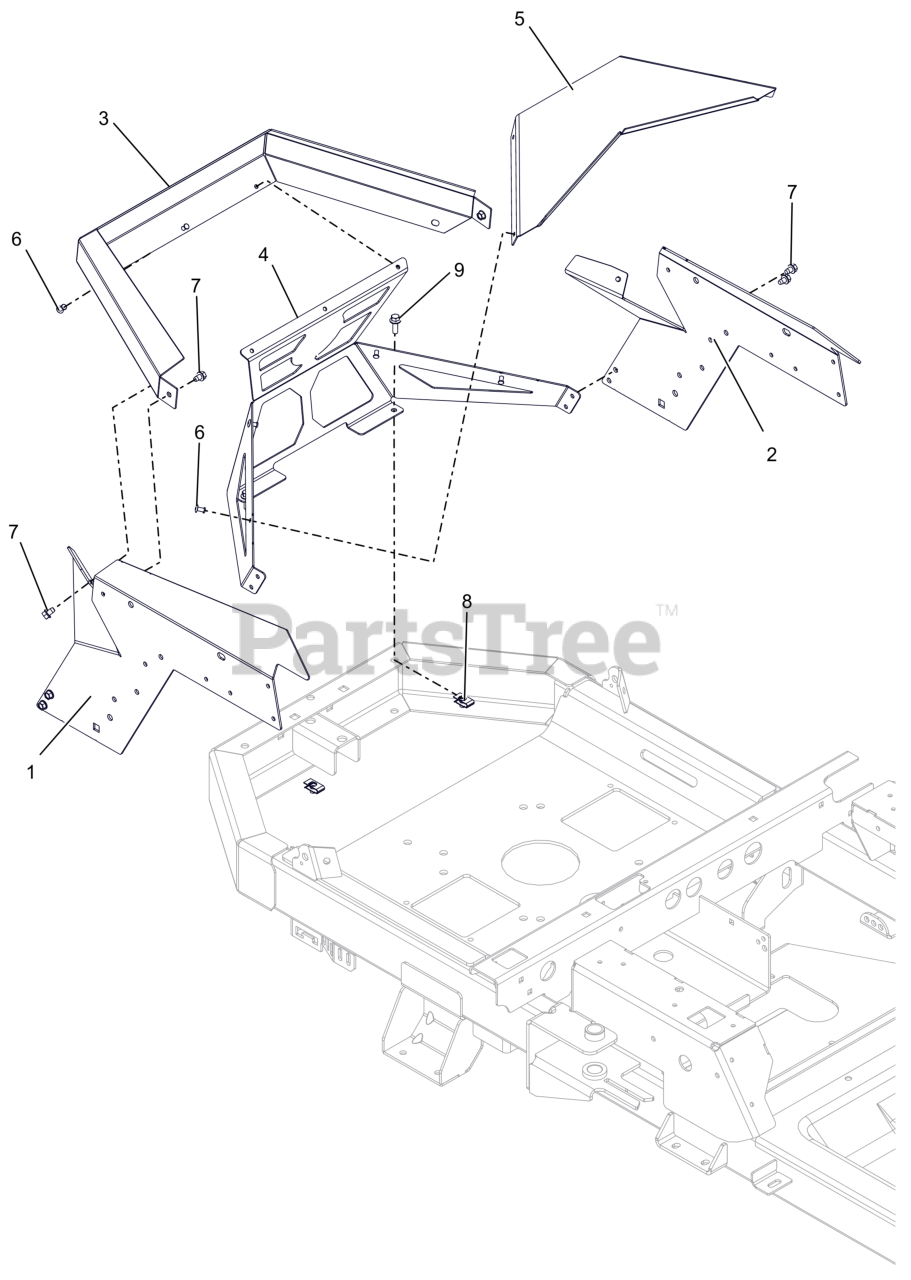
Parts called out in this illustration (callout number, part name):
1	PANEL, RIGHT REAR FENDER MOUNT
2	PANEL, LEFT REAR FENDER MOUNT
3	GUARD, ENGINE WRAP
4	GUARD, ENGINE
5	BAFFLE,ENGINE WRAP
6	RIVET, #66 STEEL POP PD BLACK
7	SCR,TAP .25-20X.375 HWH TR ZCC
8	NUT-RTNR .25-20X.56
9	BLT,HEX-FLG .25-20X.75 G5 BFP
